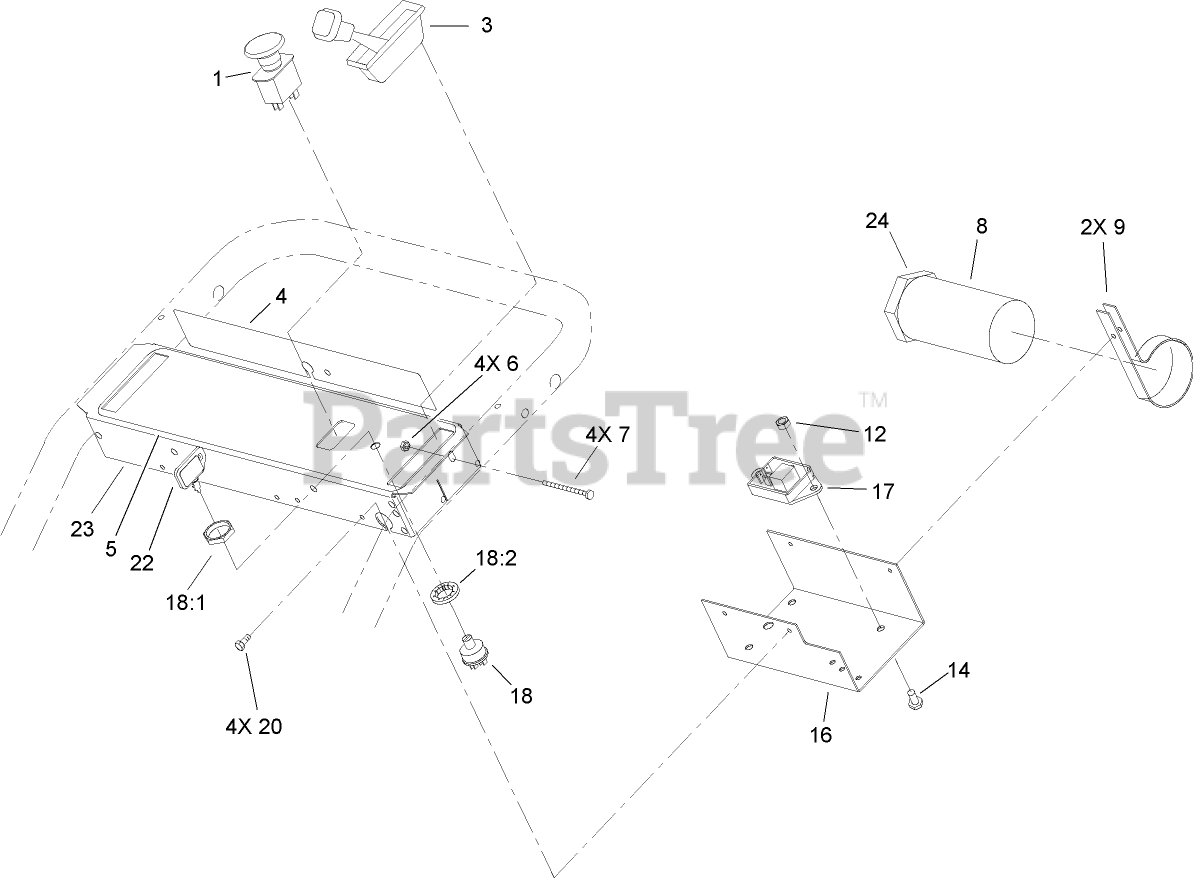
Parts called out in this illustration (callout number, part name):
1	SWITCH-PTO
3	CONTROL-THROTTLE
4	DECAL-WARNING
5	DECAL-PANEL, CONTROL
6	NUT-LOCK, NI
7	SCREW-SHH
8	TUBE-MANUAL
9	CLAMP-R
12	NUT-LOCK, NI
14	SCREW-HH
16	PANEL-BOTTOM
17	MODULE-DELAY
18	SWITCH-STARTER
18:1	NUT-HH
18:2	WASHER-TOOTH, INTERNAL
20	SCREW-HWHTF
22	KEY-IGNITION
23	PANEL-CONTROL
24	CAP-HOUSING
